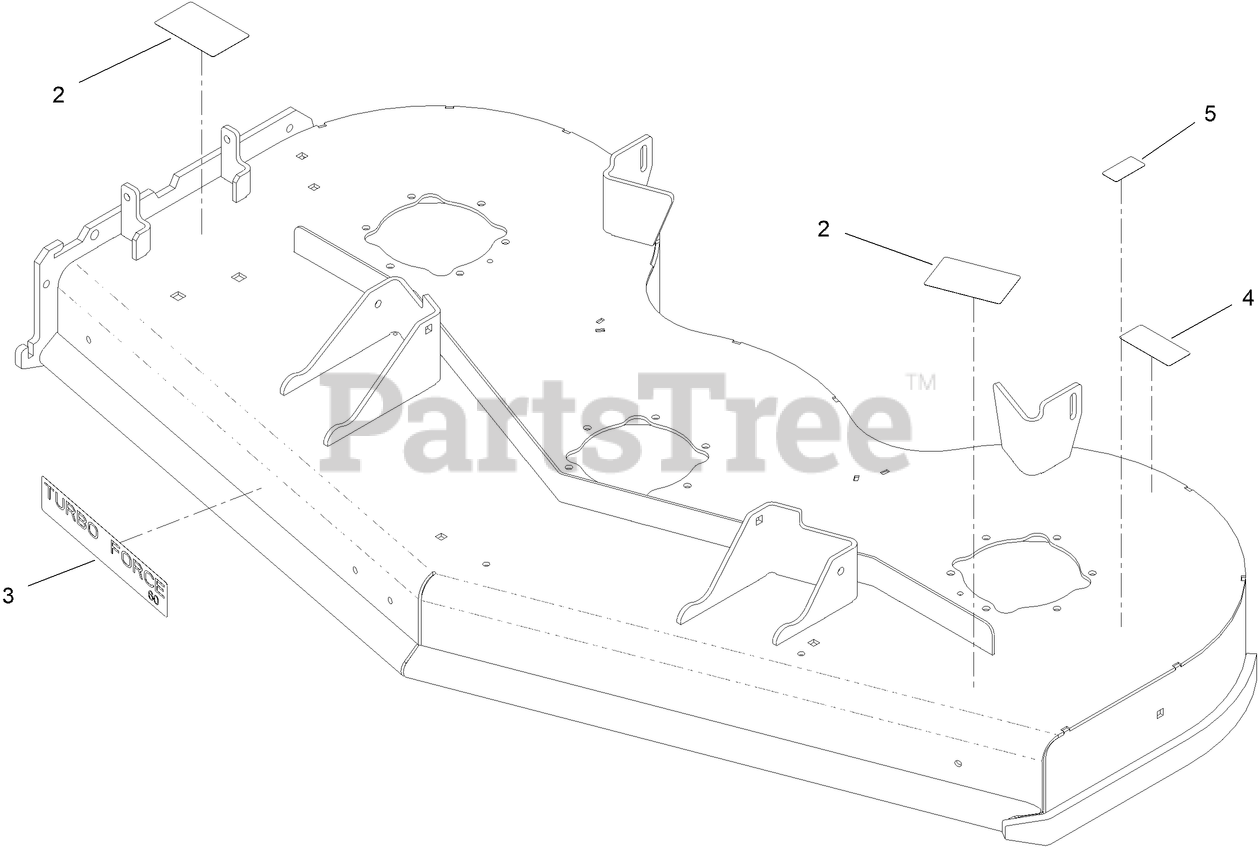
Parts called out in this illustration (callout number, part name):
2	DECAL-DANGER, CE
4	DECAL-DANGER
5	DECAL-NO SPRAY
